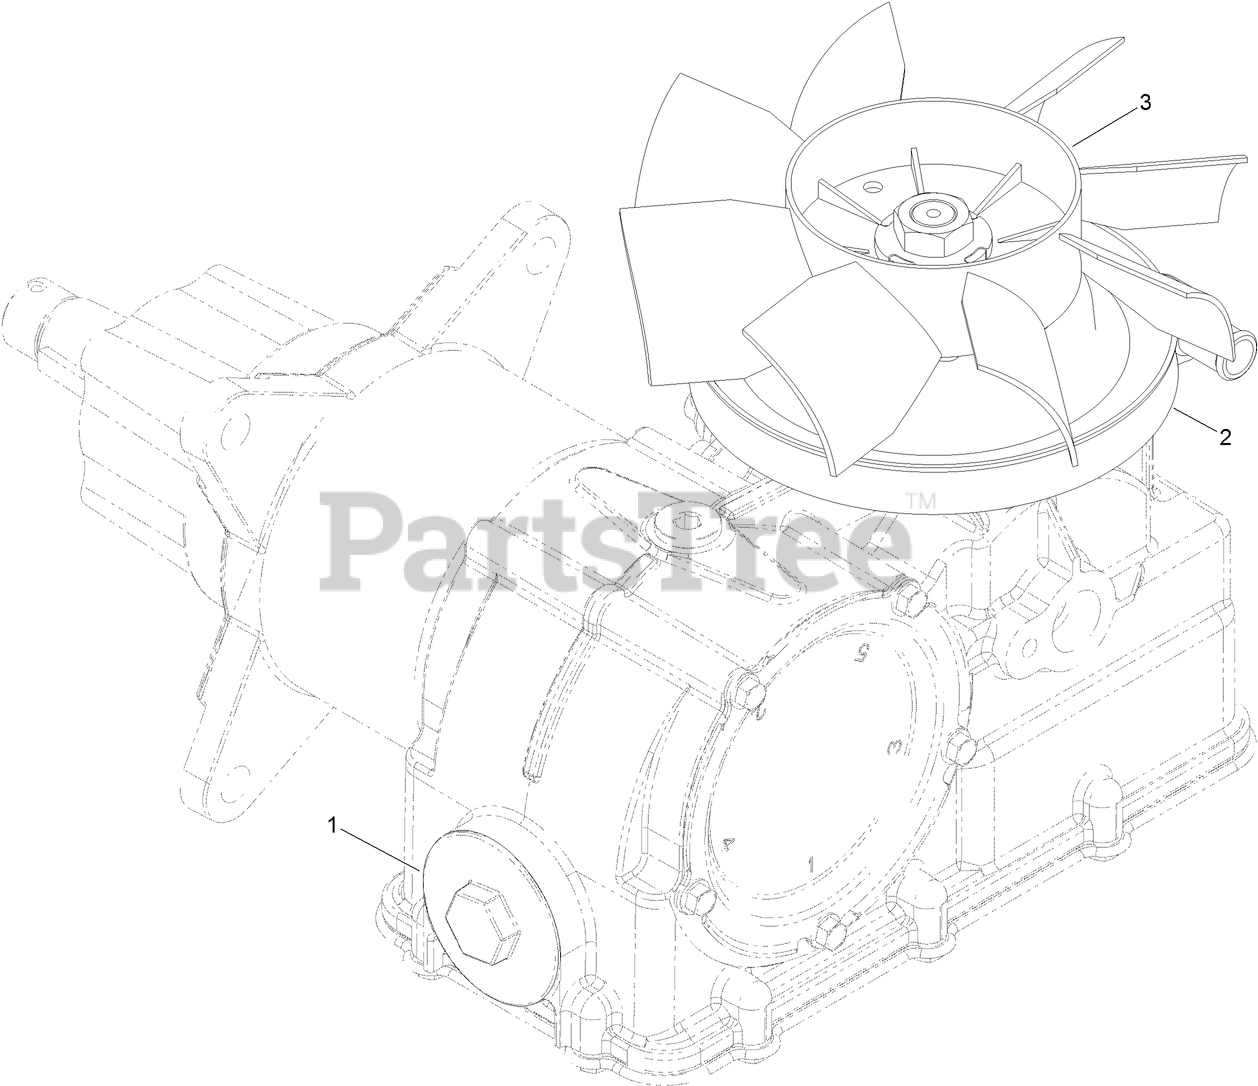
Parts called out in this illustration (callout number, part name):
1	FILTER
2	PULLEY
3	FAN (8.3 INCH)
